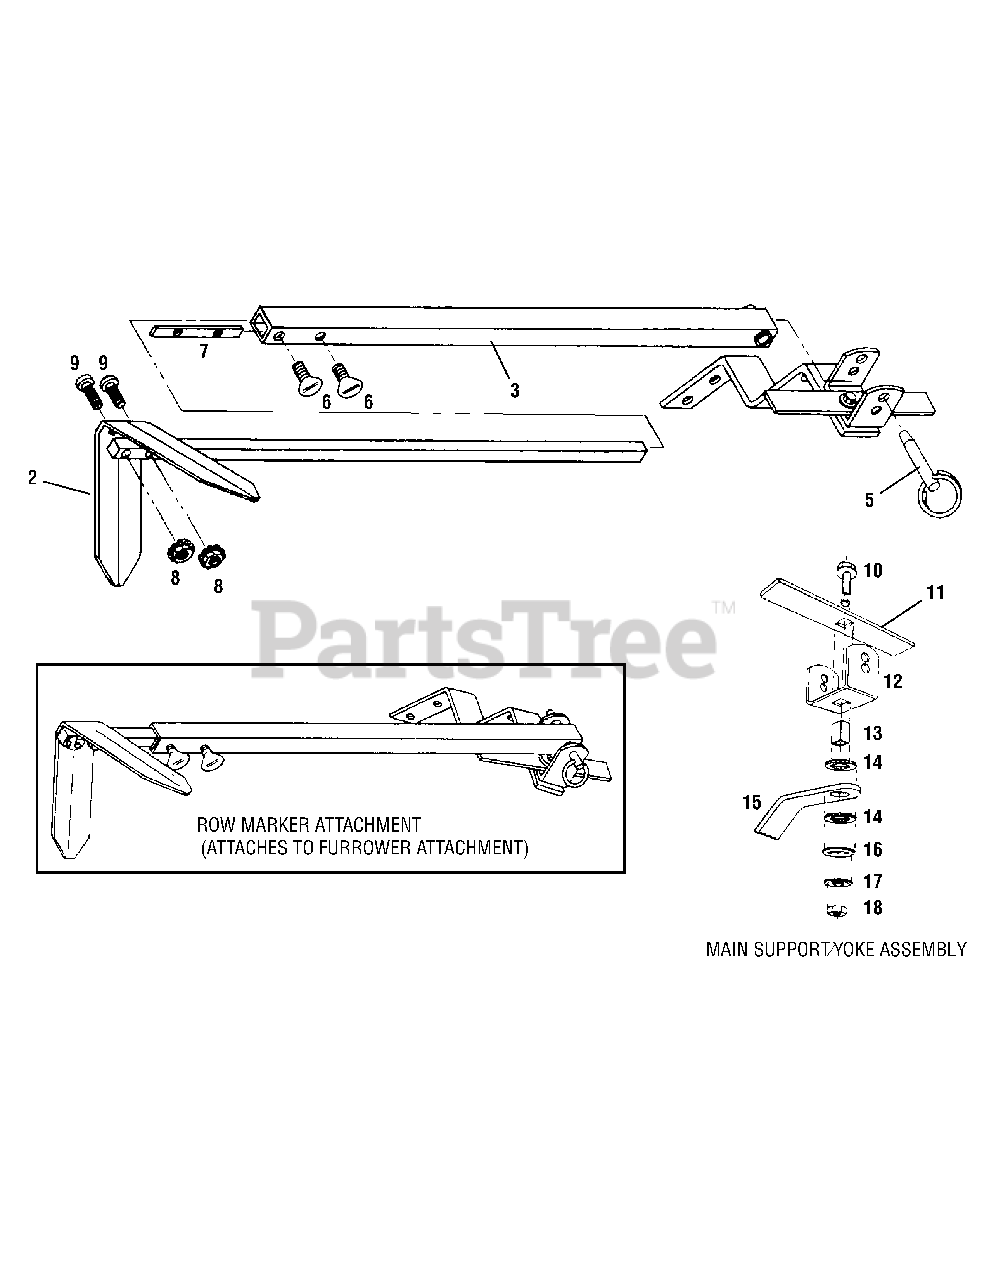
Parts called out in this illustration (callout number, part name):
1	Main Support & Yoke Assy
2	Marker Blade-blade only
3	Marker Arm-main arm
4	Marker Arm-extension arm with pin
5	Hitch Pin
6	Thumbscrew-1/4-20 x 1/2
7	Nut Bar
8	Nut-hex, 10-24 w/ attached star washers
9	Screw-round hd.,10-24
10	Screw-hex flanged locking,3/8-16 x 1-1/2
11	Stop Bar
13	Tube Key-square
14	Washer-friction
15	Main Support
16	Washer-square hole
17	Washer-disc spring
18	Nut-hex 3/8-161
